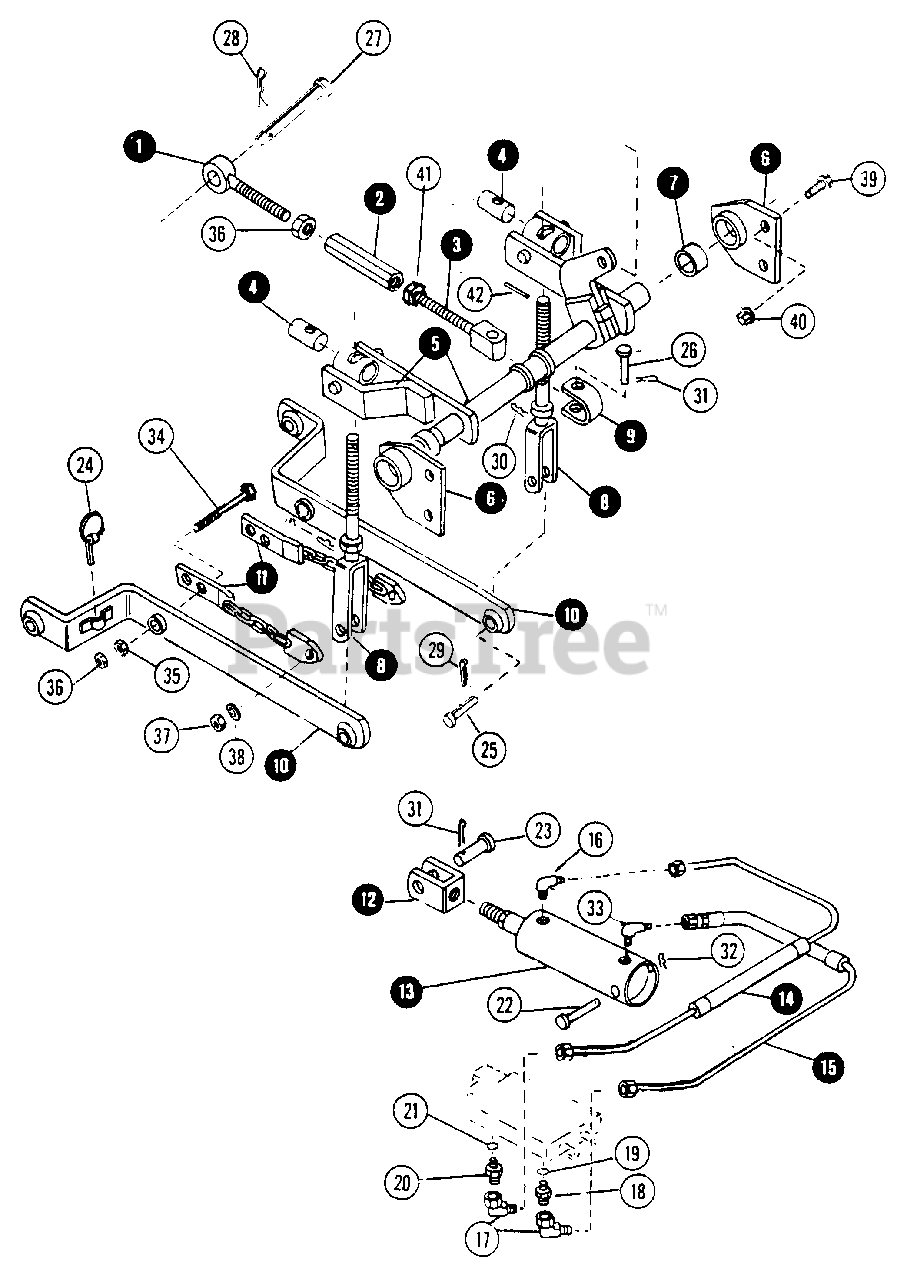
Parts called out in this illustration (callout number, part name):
1	CLEVIS, LINK ADJUSTER
2	ADJUSTER, UPPER LINK
3	CLEVIS, UPPER
4	SWIVEL, LOWER LINK
5	ROCKER - SHAFT, (ASSEMBLY)
6	PIVOT, ROCKERSHAFT
7	BUSHING, PIVOT
8	LINK, LOWER ADJUSTER
9	STRAP, CLEVIS TO SHAFT
10	LINK, LOWER LIFT
11	CHAIN, CHECK (ASSEMBLY)
12	END, CYLINDER ROD
13	CYLINDER, HYDRAULIC LIFT
14	TUBE & HOSE ASSEMBLY - VALVE TO CYLINDER
15	TUBE & HOSE ASSEMBLY - VALVE TO CYLINDER
16	ELBOW, 1/4-18
17	ELBOW, 90 DEGREE SWIVEL
18	CONNECTOR, ELBOW TO VALVE
19	O-RING, 906 (.08 x .47 I.D.)
20	CONNECTOR
21	O-RING, 908 (.09 x .64 I.D.)
22	PIN, CLEVIS - CYLINDER TO FRAME
23	PIN, CLEVIS - LINK TO FRAME
24	PIN
25	PIN, CLEVIS - LINK TO FRAME
26	PIN, CLEVIS - CLEVIS TO SHAFT
27	PIN, CLEVIS - 5/8 x 3"
28	PIN, HAIR
29	COTTER-PIN, 3/16 x 1-1/4
30	PIN, HAIR - CLEVIS TO SHAFT
31	COTTER-PIN, 5/32 x 1
32	PIN, HAIR - CYLINDER to FRAME
33	ELBOW, 1/4-18 Extra Long
34	BOLT, 5/8C x 3-1/2 HEX HEAD
35	NUT, 5/8C HEX
36	NUT, 5/8C HALF HEX
37	NUT, 3/8C HEX LOCK
38	WASHER, 3/8" Flat
39	BOLT, 1/2C x 1-1/4 HEX WASHER HEAD
40	NUT, 1/2C HEX FLANGE
41	JAM-NUT, 5/8C LEFT HAND THREAD
42	PIN, 1/4 x 2-1/2 GROOVE
